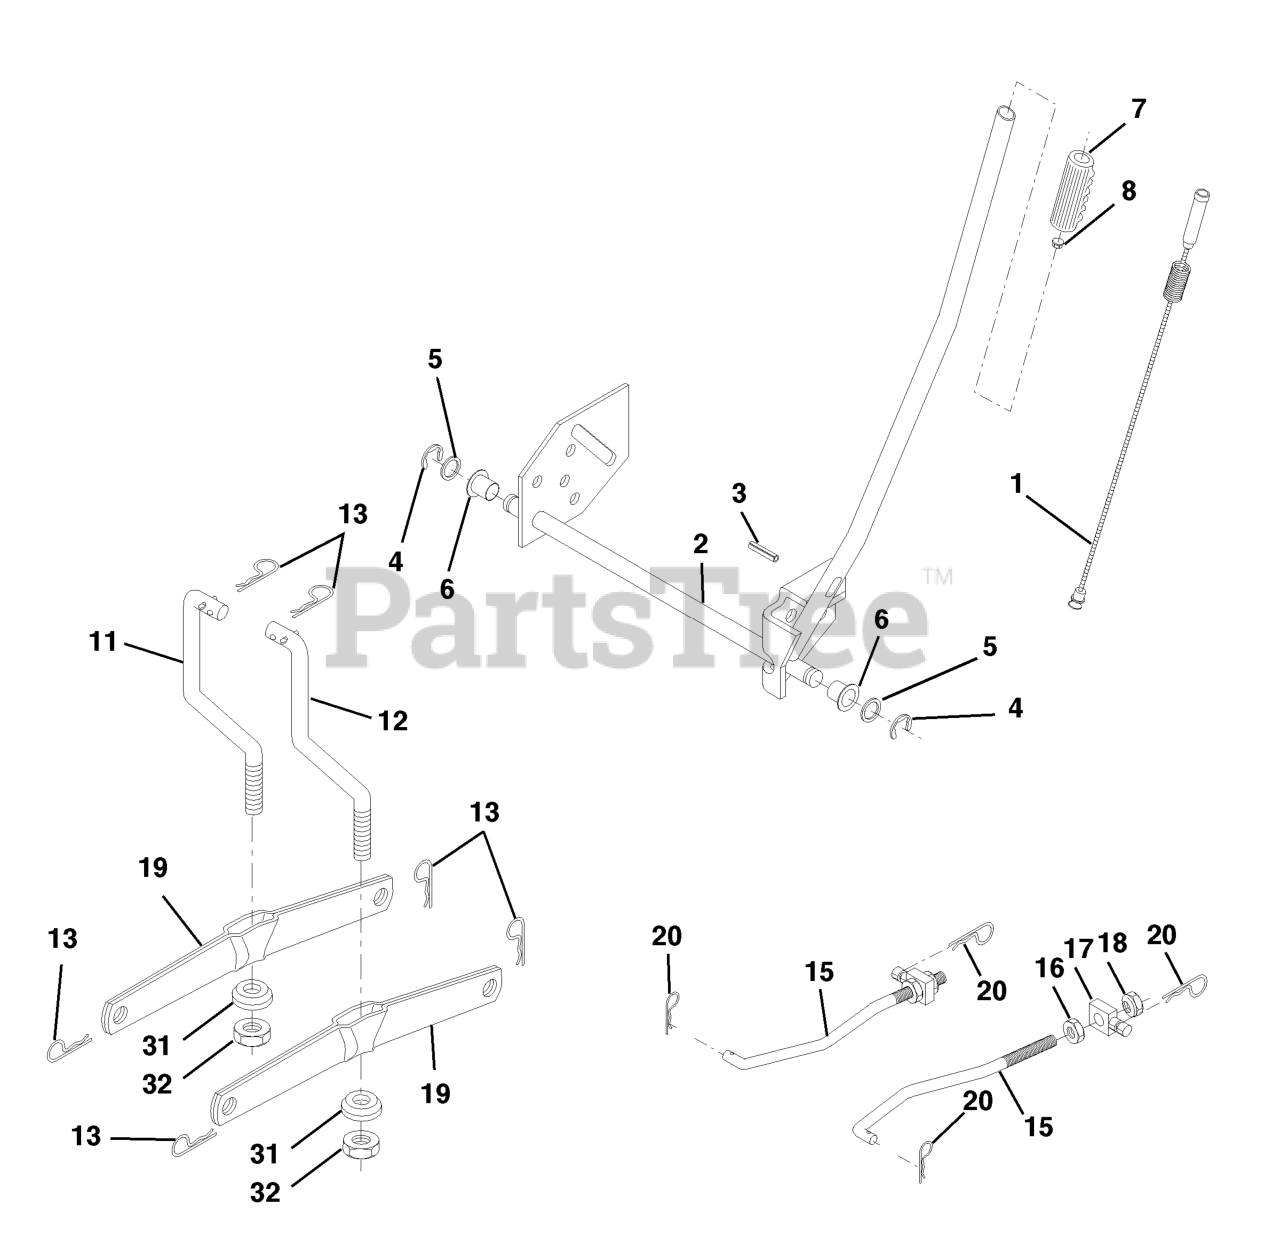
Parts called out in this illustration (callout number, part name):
1	WIRE ASM INNER W/ PLUNGER LT
2	SHAFT ASM R HANDLE
3	PIN GROOVE.
4	RETAINING RING LT
6	BEARING.NYLON
8	PLUNGER BUT KIT
11	LINK LIFT LH
12	LINK LIFT RH
13	RETAINER-SPRNG RB
15	FRONT LINK
16	NUT.HEX.JAM.1/2-13
17	TRUNION
18	NUT.LK.W/WSH.1/2.
19	ARM.REAR.SUSPENSION
20	SPRING RETAINER
31	BEARING PIVOT
32	NUT CROWNLOCK 3/8-24
